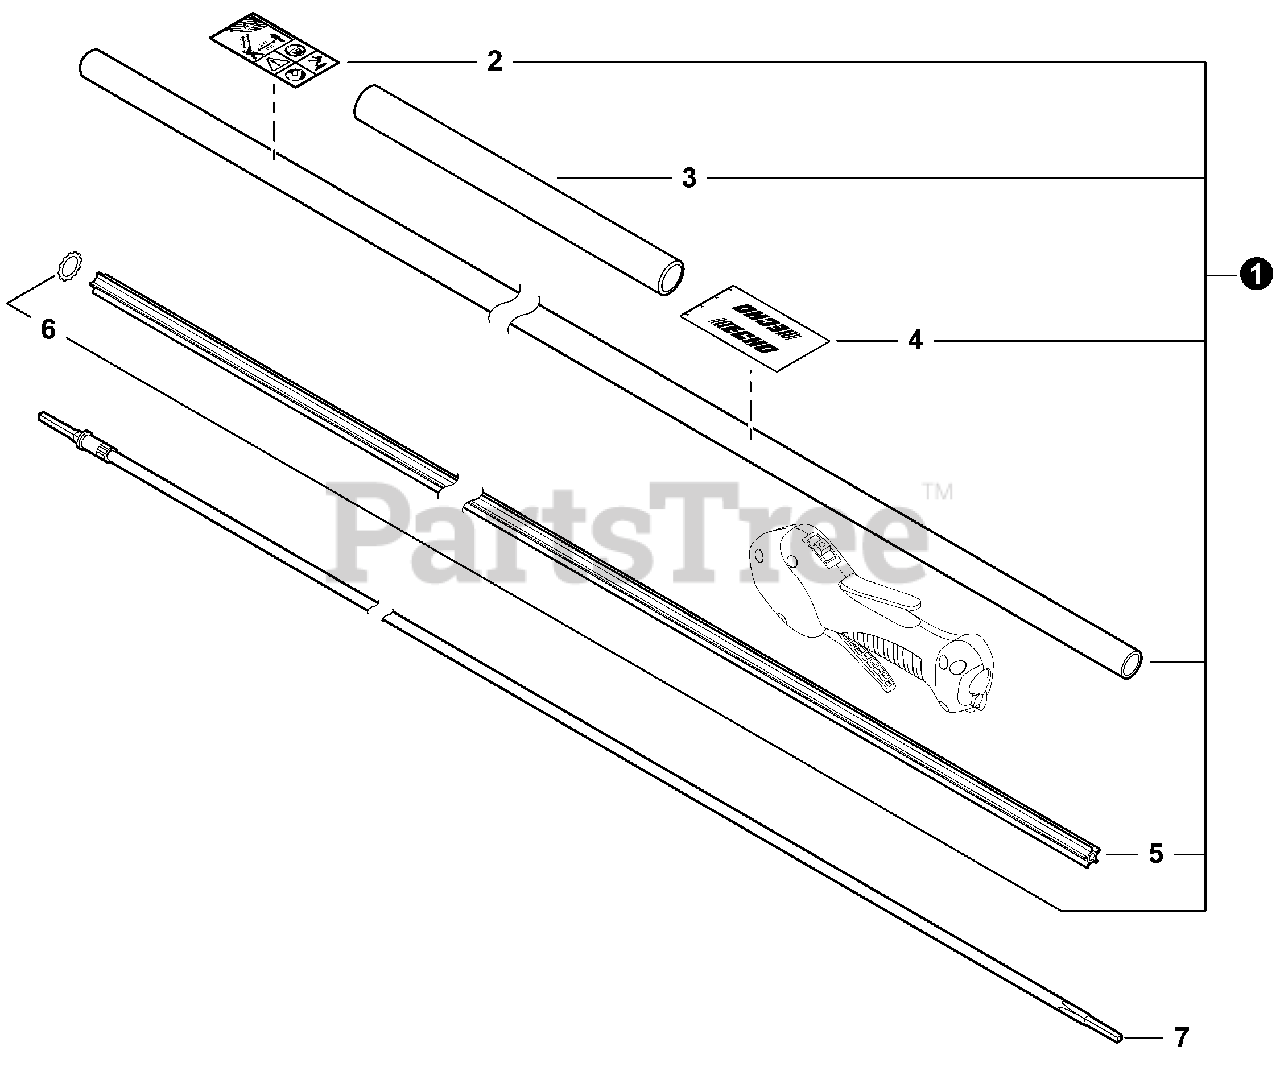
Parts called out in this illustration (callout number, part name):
1	MAIN PIPE ASSY
2	LABEL, CAUTION
3	GRIP, FRONT
4	LABEL, HANDLE LOCATION
5	LINER - FLEXIBLE
7	DRIVESHAFT - FLEXIBLE
